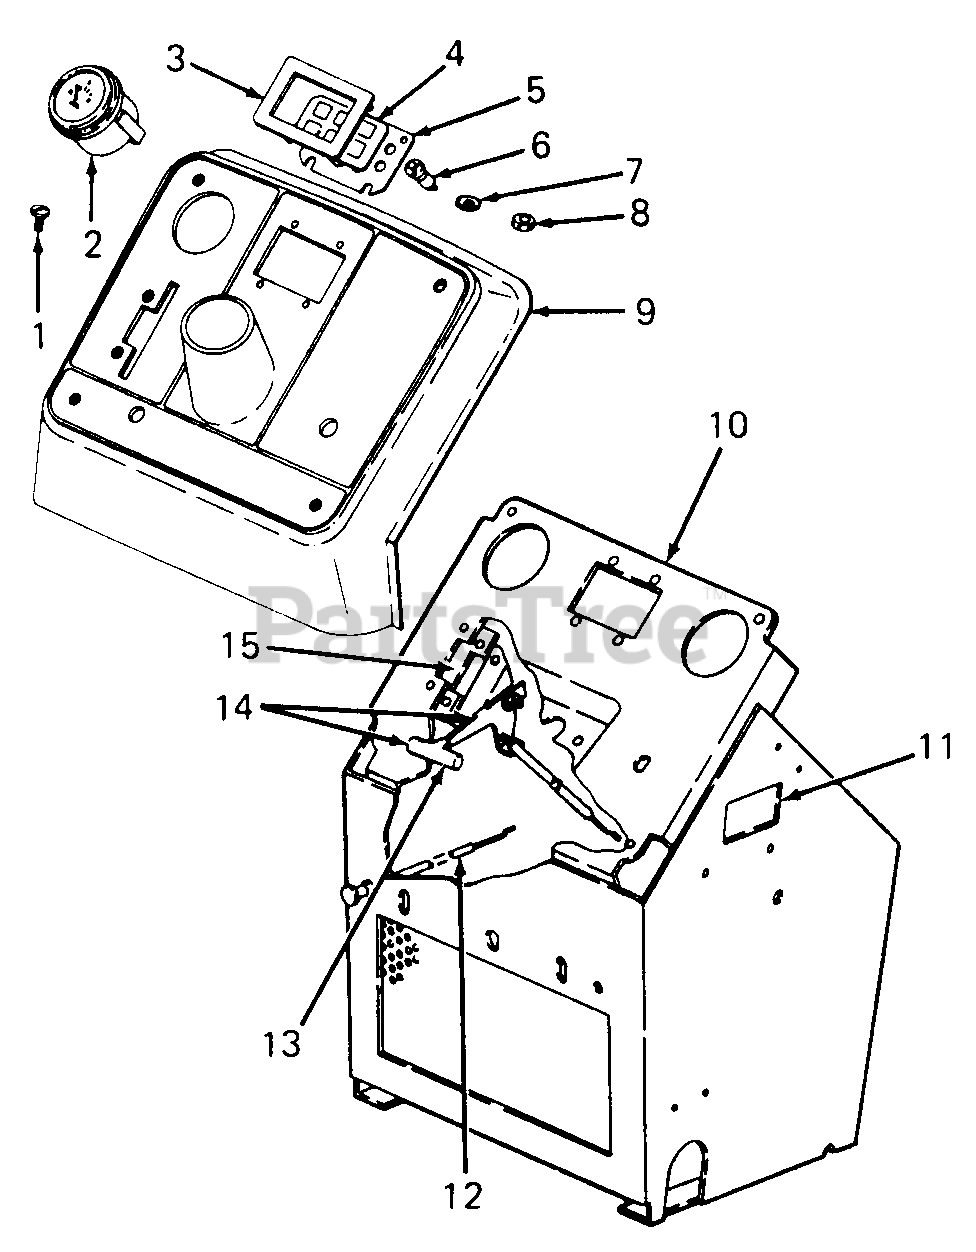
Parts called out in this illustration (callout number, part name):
1	Screw, 10-24 X 3/4 Pan-Hd. Cutting
2	Indicator, Charge
3	Bezel, Light
4	Label, Indicator
5	Plate, Indicator
6	Lamp, Indicator
7	Washer, .18 X .50 X. 06 Rubber
8	Nut, Self-Threading Pal
9	Panel, Instrument
11	Label, Battery Booster
12	Control, Choke
13	Knob, Throttle Control
14	Control, Throttle
15	Plate, Throttle Closure
